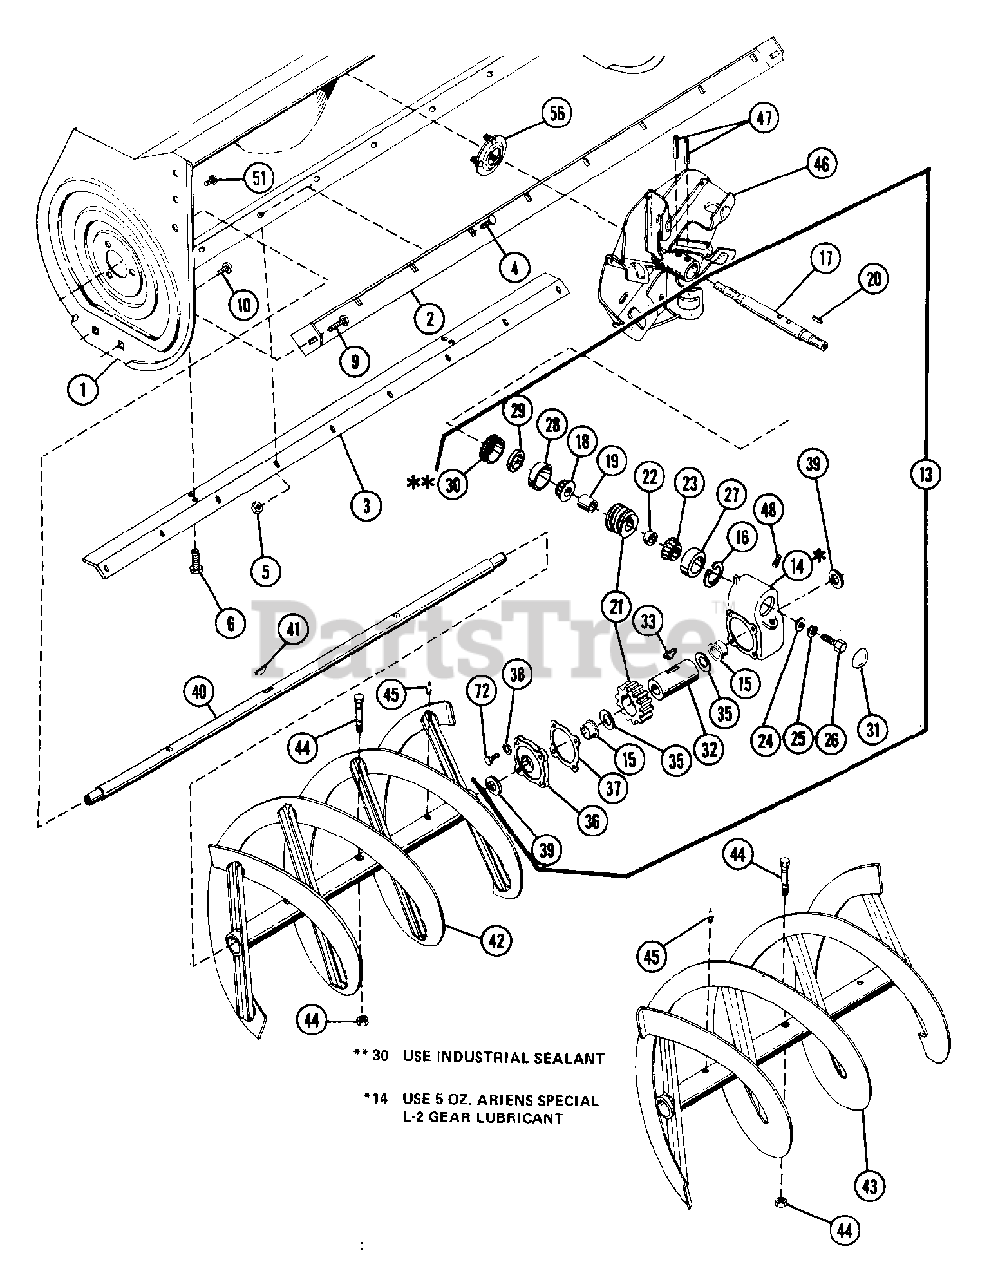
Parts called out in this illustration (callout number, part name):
1	BLOWER HOUSING ASSEMBLY
2	SCRAPER BLADE
3	SCRAPER BLADE BRACE
4	BLT-RDHDSQNK .31-18X.75 GR5 PL
5	NUT-LK .312-18 GR A PL
6	BLT-HEX .38-16X.75 PL GR5
9	BLT-RDHDSQSHNK .38-16X1.00 PL
10	BLT-RDHDSQNK .38-16X.75 SHT PL
13	GEAR CASE - CAST IRON
14	GEAR CASE - CAST IRON
15	BSHG-FLG .683X1.87X1.68X2.250
16	RG-RTNG INT 1.781 HSG X.062
17	WORM SHAFT
18	BRG-CONE 1.0X.58
19	BEARING SPACER 1.032X1.25X1.78
20	KEY-SQ .188X1.0X.188 SAE 8630
21	WORM & GEAR ASSEMBLY
22	BSHG, SPCR .755X1.12X.50 PM
23	BRG-CONE .750X.61
24	WSHR-FL-STL .328X1.0X.094
25	WSHR-LK .312X.097 PL HVY
26	BLT-HEX .31-18X.75 PL GR2
27	BRG-CUP 1.781X.475
28	BRG-CUP1.980X.420
29	SEAL 1.125X1.375X.125
30	ADJUSTMENT PLUG
31	DUST CAP
32	GEAR CASE SHAFT
33	KEY-FTHR .25X.875X.312
35	WSHR-FL-STL 1.625X2.500X.012
36	GEAR CASE COVER
38	WSHR-LK-EXT. 250 ID
39	SEAL 1.625X2.125X.250
40	RAKE SHAFT
41	KEY-WDRF .25X.875X.375 SAE A
42	RAKE, RIGHT-48(1.12ID X 15.75)
43	RAKE, LEFT-48"(1.12ID X 15.75)
44	SHEAR BOLT & NUT ASSEMBLY
45	SPIN DRIVE ZERK FITTING
47	PIN-ROLL .313X1.75
48	PIPE PLUG
51	SCR-SLTR-SERNK .25-20X.62 PL
56	BEARING FLANGE
72	BLT-HEX .25-20X.75 PL GR2
